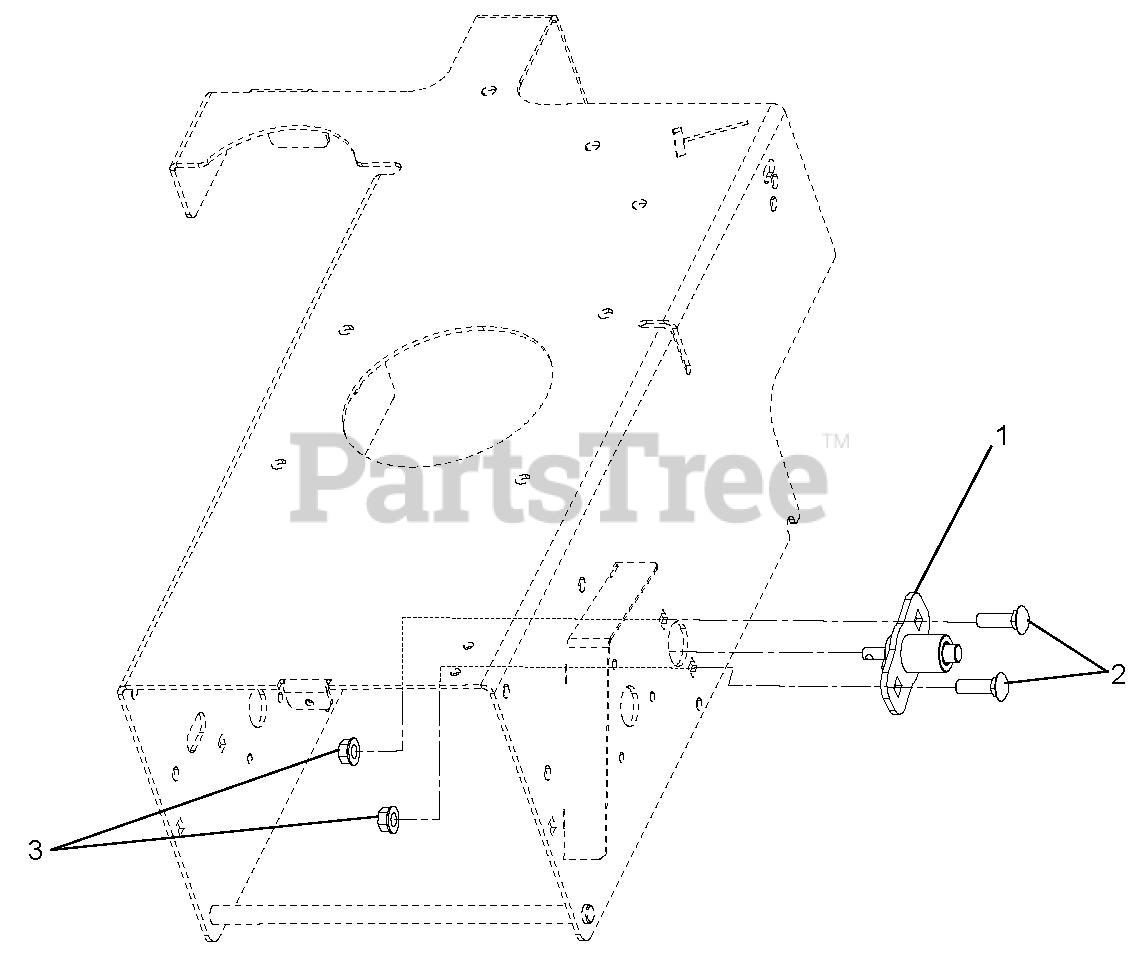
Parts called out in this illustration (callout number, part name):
1	Kit, Pin Brake
2	Bolt, Round Head Square Neck .38-16 x 1.25
3	Nut, Flange .375-16
